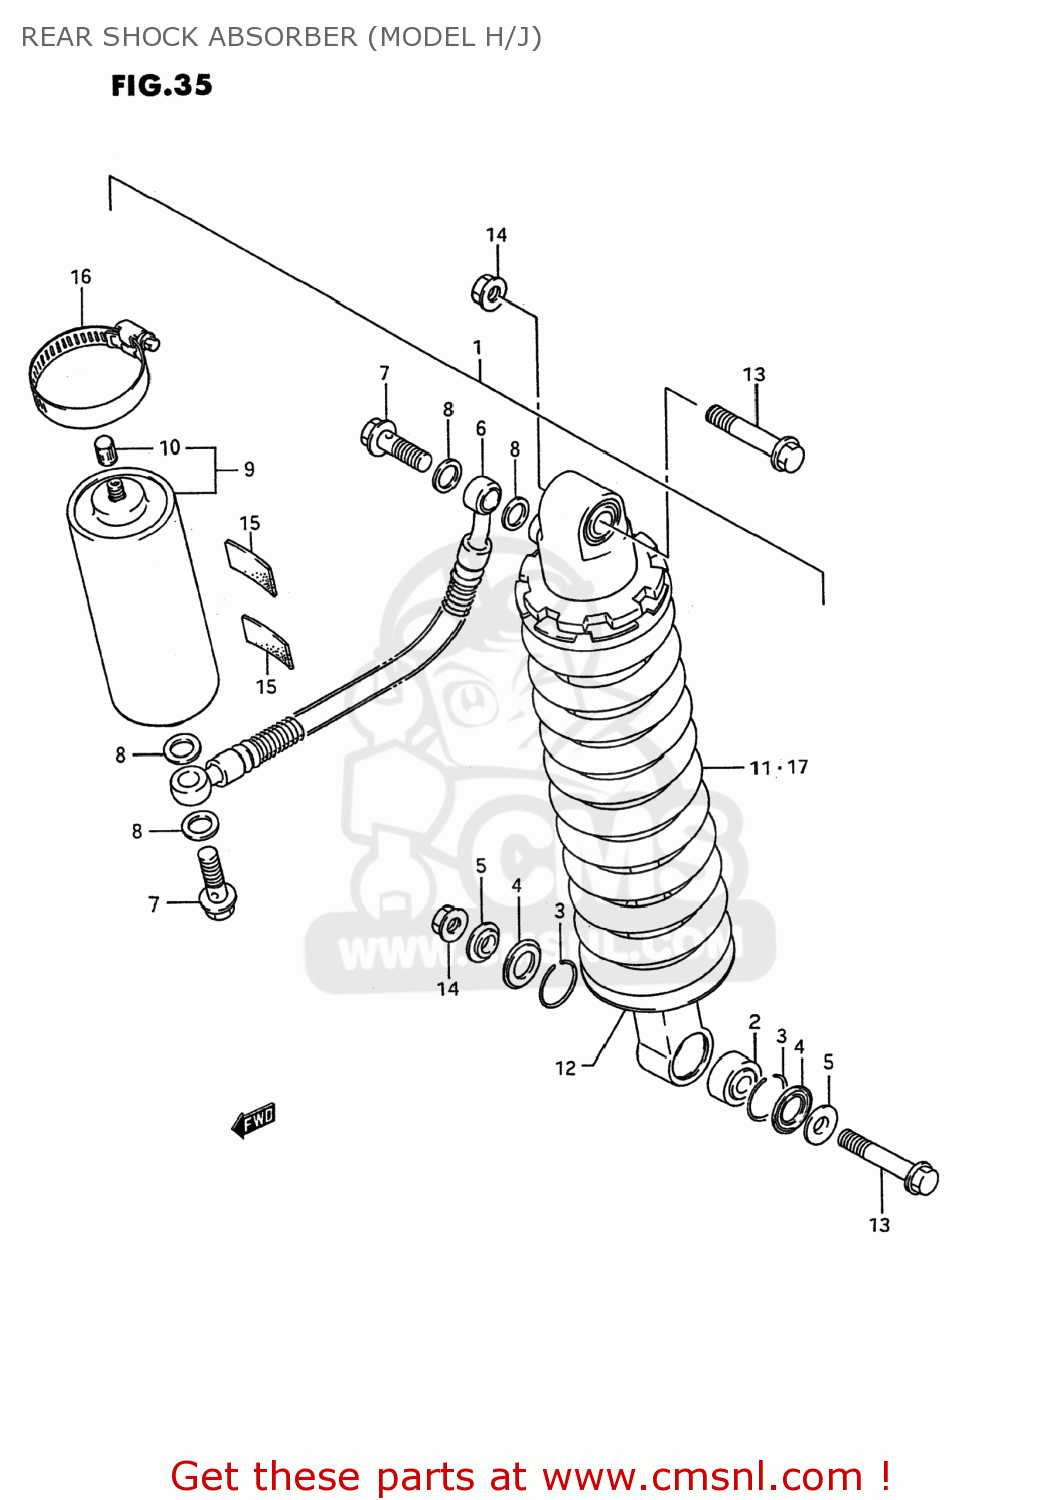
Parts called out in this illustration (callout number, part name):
1	ABSORBER ASSEMBLY,REAR SHOCK
2	BEARING,REAR SHOCK ABSORBER
3	RING
4	DUST SEAL,RR SHOCK
5	COLLAR
6	HOSE
7	BOLT,REAR SHOCK ABSORBER
8	WASHER(10X15X1.5)
9	RESERVE TANK,REAR SHOCK
10	CAP,VALVE AIR
11	SPRING
12	SEAT
13	BOLT,RR CUSHION ROD UPR
14	NUT
15	CUSHION,REAR SHOCK ABSORBER
16	CLAMP
17	SPRING (HARD)
